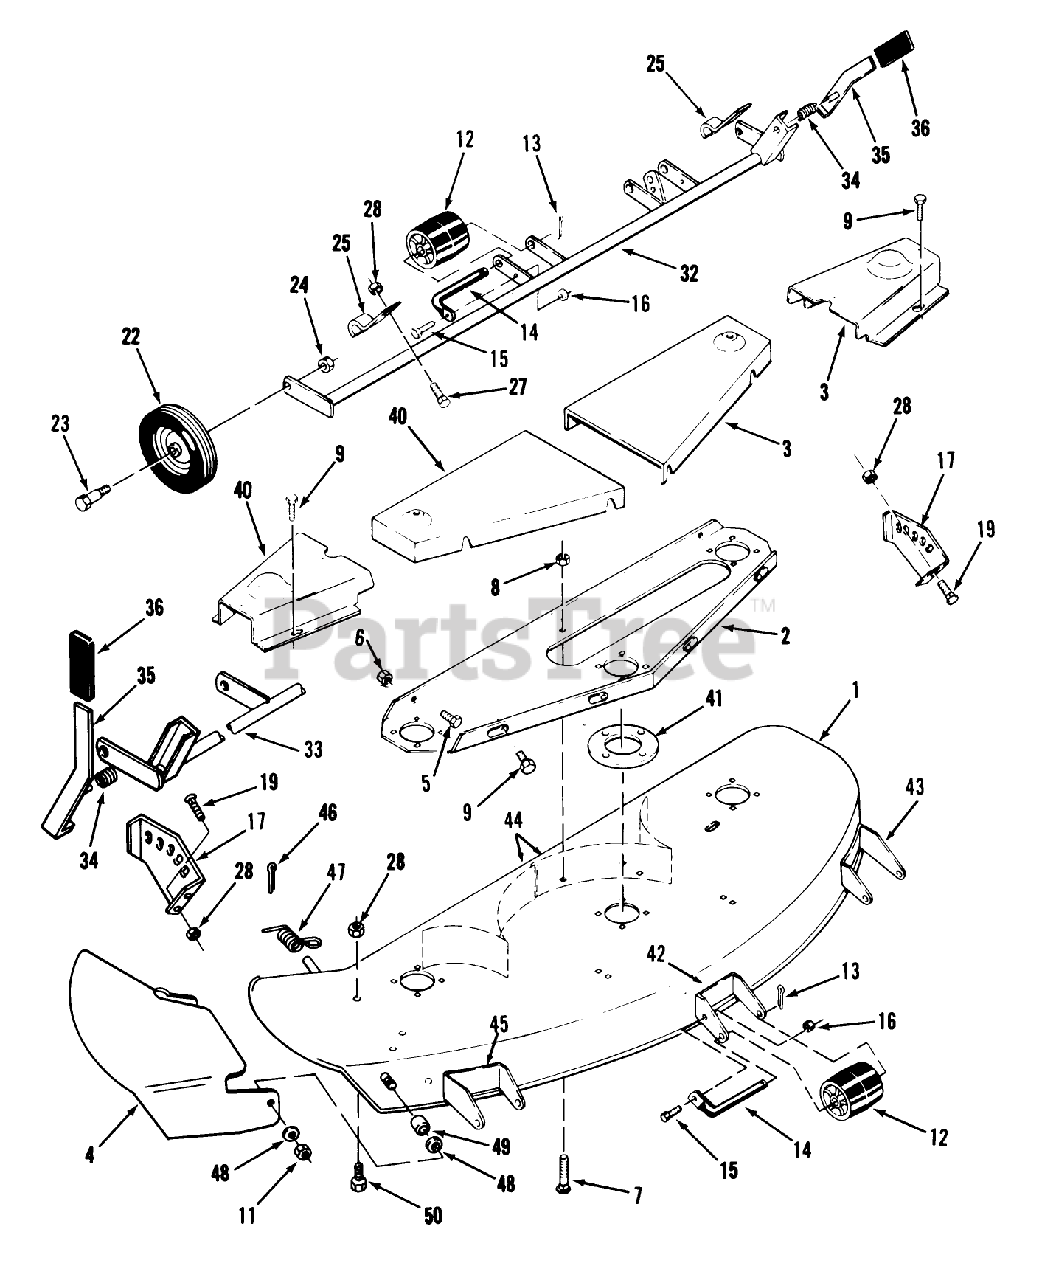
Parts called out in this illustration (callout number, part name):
9	Bolt
14	ROLLER-SHAFT
22	WHEEL
23	BOLT-SHOULDER
34	SPRING-COMPRESSION
41	PLATE-SPINDLE
43	BRKT-ROLLER
44	BAFFLE-DECK L.H.
44	BAFFLE-DECK R.H.
44	BAFFLE-DECK RH
49	BUSHING-PIVOT
